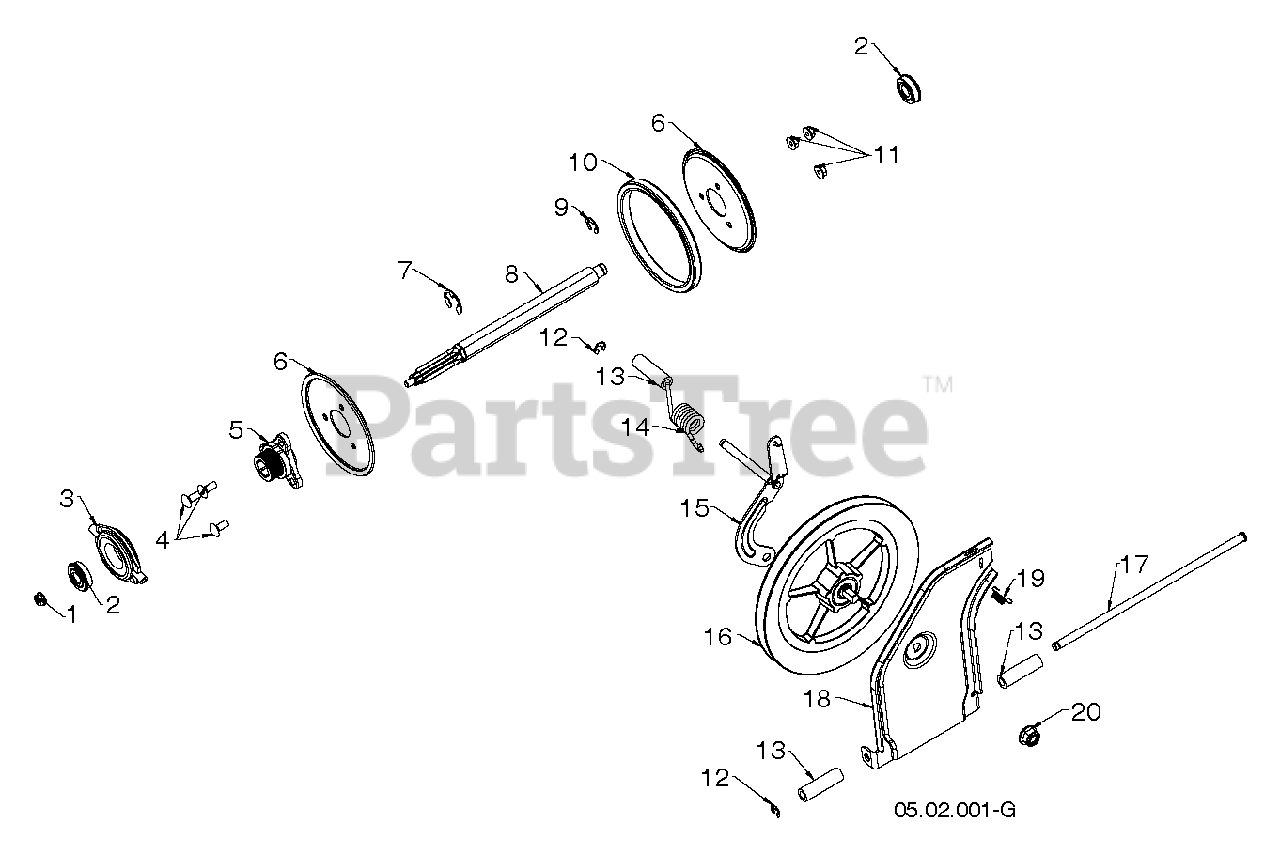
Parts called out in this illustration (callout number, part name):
1	Flange Hex Lock Nut, 5/16-18
2	Bearing, 9/16" Id. Snr
3	TRUNNION BEARING ASSY
4	BOLT.5/16-18.
5	HUB.RUBBER.WHEEL
6	Wheel Plate, Rubber Black
8	Reduction Shaft, 7T
9	Retaining Ring
10	Ring, Rubber
11	NUT.LOCK.5/16-18
13	SPACER YOKE, TORSION SPRING
14	Drive Torsion Spring
16	Friction Disc Combo Pulley
17	ROD.TIP.PLATE
18	Plate, Swing Friction Pulley 47
19	SPRING LATCH
20	NUT, 1/2-13 HEX FLG NYLOC ZD
